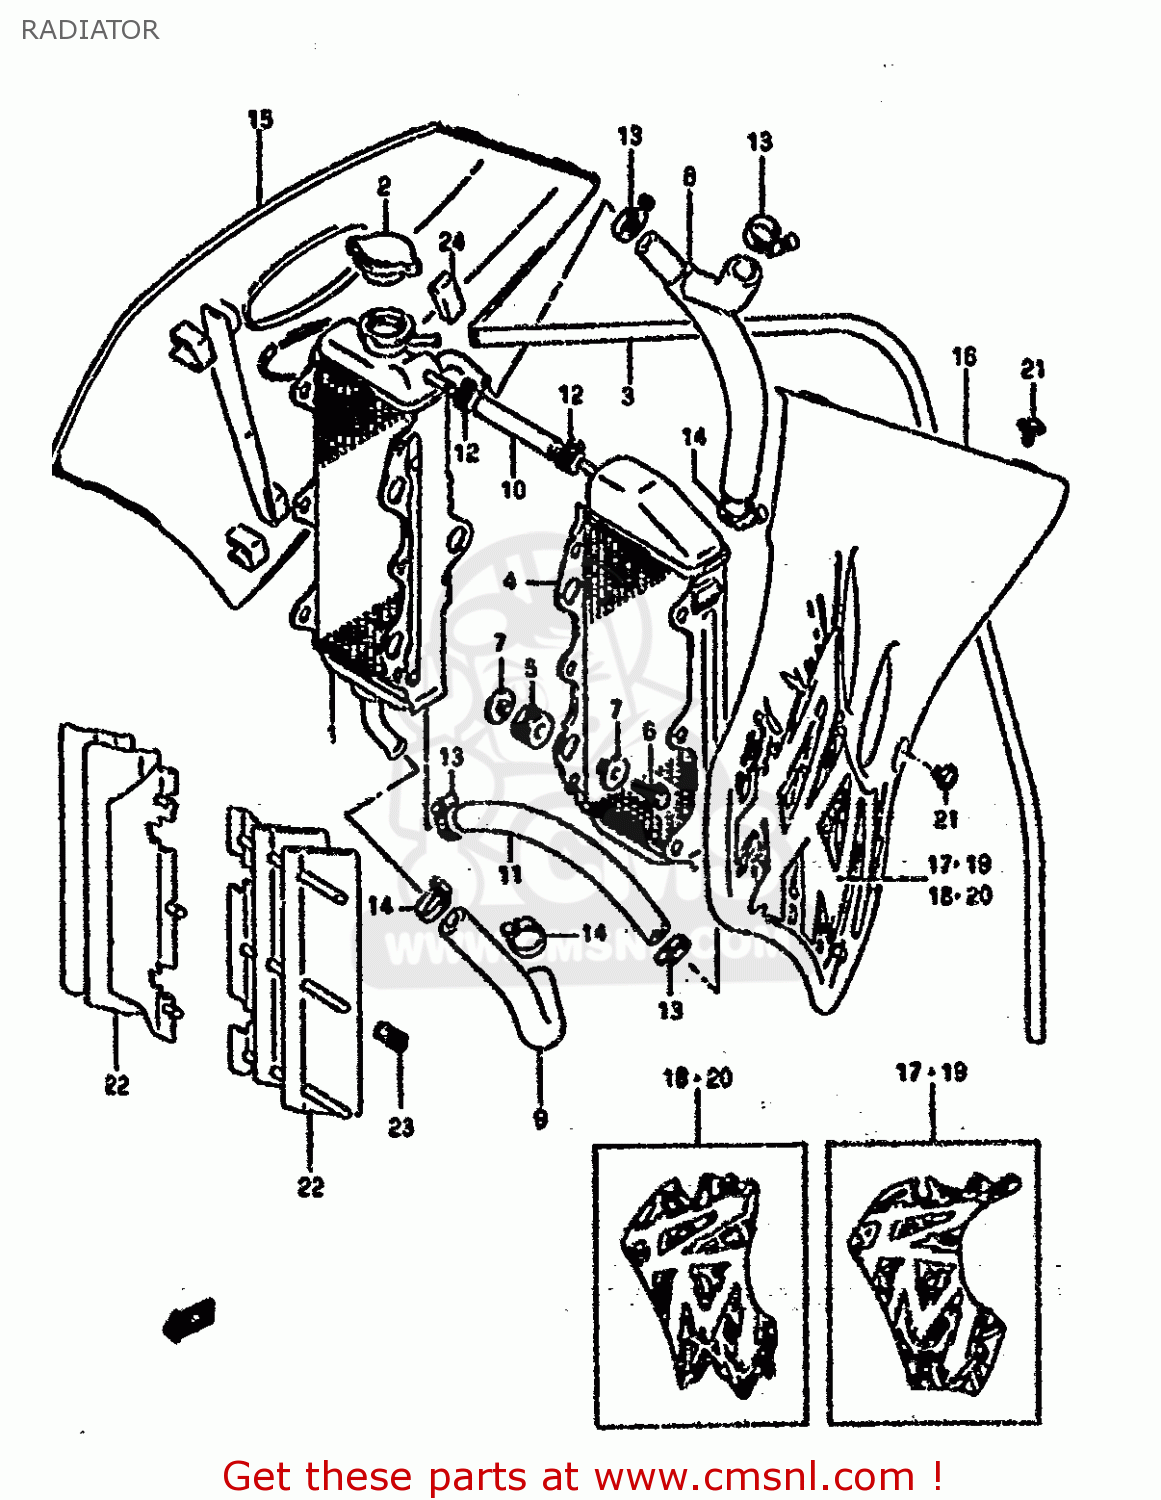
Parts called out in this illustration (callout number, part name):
1	RADIATOR,WATER,R
2	CAP,RADIATOR
3	HOSE(5X8X2000)
4	RADIATOR,WATER,L
5	CUSHION,RADIATOR LWR
6	BOLT
7	WASHER,RDTR SPRT
8	HOSE,RADIATOR INLET
9	HOSE,RADIATOR OUTLET
10	HOSE,WATER
11	HOSE,RADIATOR JOINT NO.2
12	CLIP
13	CLAMP
14	CLAMP
15	COVER,RADIATOR
16	COVER,RADIATOR
17	EMBLEM,RADIATOR COVER
18	EMBLEM,RADIATOR COVER
19	EMBLEM,RADIATOR COVER
20	EMBLEM,RADIATOR COVER
21	SCREW(6X12)
22	LOUVER,RADIATOR
23	SPRING
24	CUSHION,RADIATOR COVER
